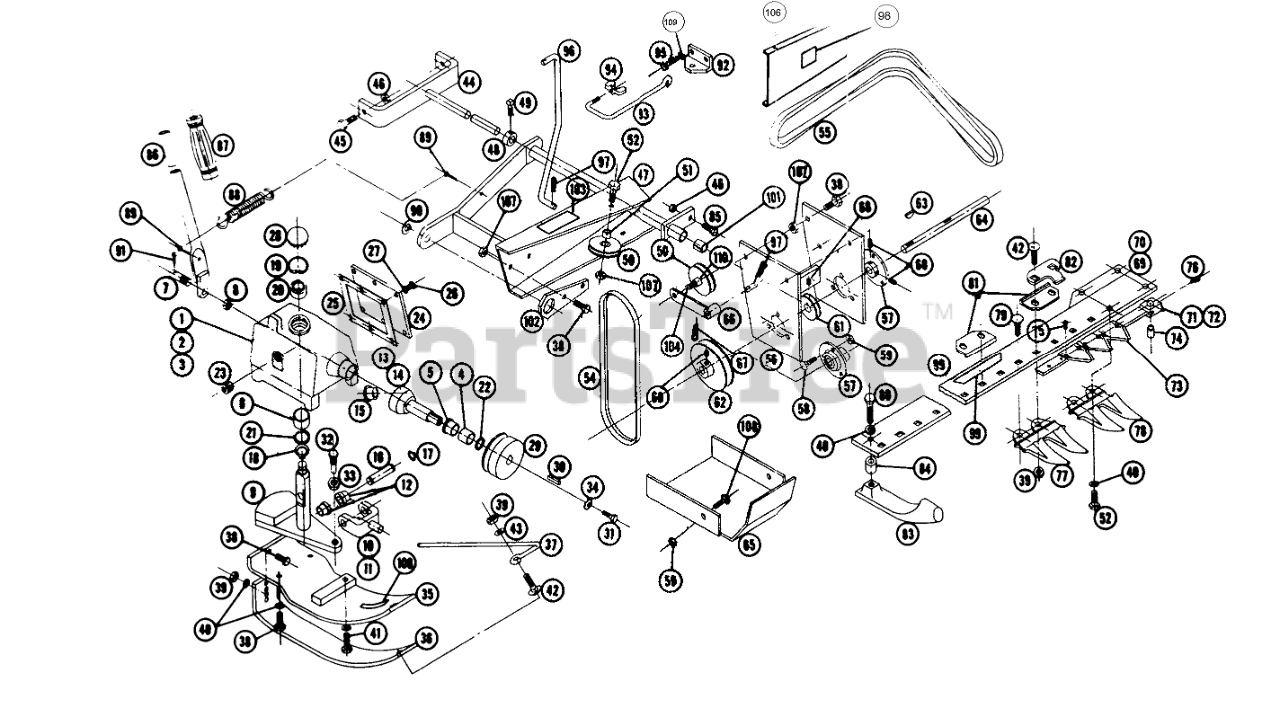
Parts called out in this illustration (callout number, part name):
1	Ass-y Housing Complete-Sickle Drive
2	Ass-y Housings & Bearings
3	Housing
4	Bearing-Bronze Sleeve
5	Bearing-Bronze Sleeve
6	Bearing-Bronze Sleeve
7	Pin
8	Nut, 3/4-16
9	Ass-y. Shaft-Weldment
10	Ass-y. Yoke
11	Yoke
12	Bearing-Bronze Sleeve
13	Ass-y. Shaft & Bearing
14	Shaft
15	Bearing-Bronze Sleeve
16	Pin Yoke
17	SNAP RING- 5/8 EXT
18	SNAP RING
19	Ring-Snap
20	Bearing-Ball
21	Seal 1 1/4 I.D.
22	Seal
23	Plug 1 x 11 1/2 NPTF
24	Cover Plate
25	Gasket
26	Screw-Rd. Hd. #10-24 x 3/8
27	Lockwasher #10
28	Plug Button
29	Pulley 4 Dia.
30	KEY-STRAIGHT
31	Bolt 3/8-16 x 7/8
32	Pin Sickle Drive
33	Nut-5/8-18
34	WASHER
35	Ass y. Shoe-Upper-Weldment
36	Shoe-Lower
37	Rod-Gross
38	Bolt 3/8-16 x 1
40	Lockwasher
41	Bolt, 3/8-16 x 1/2
42	Bolt Carriage 3/8-16 x 1
43	Washer
44	Ass-y. Bracket & Rod
45	Bolt Hex 1/2-13 x 1
46	Locknut-1/2-13
47	Ass-y Frame
48	Collar
49	Screw-Set
50	Pulley
51	SPACER
52	Bolt 3/8-16 x 1
54	Belt
55	V BELT
56	Ass-y. Shaft Support-Weldment
57	Bearing-Flanged
58	Bolt Hex 5/16-18 x 3/4
59	Nut-Nylock 5/16-18 Hex.
60	Set Screw 5/16-18 x 5/16
61	Pulley
62	Pulley
63	Key
64	Shaft
65	Shield Pulley
66	Ass-y. Idler Arm-Weldment
67	Hairpin
68	Set Screw 1/4-20 x 1/4
69	Ass-y. Cutter Bar Complete 42"
70	Ass-y. Bar-Guard
71	Ass-y. Knife Bar & Sections
72	Ass-y. Knife Bar-Weldment
73	Section
74	Bushing
75	Rivet
76	ZERK 90DEGREE
77	Twin Guard
78	Guard Cutter Bar
79	Bolt 3/8-16 x 1
80	Bolt, 3/8 16 x 2
81	Wear Plates
82	Clip, Hold Down
83	Skid
84	Spacer
85	Bolt-Hex. 1/2-13 x 2 3/4
86	Ass-y. Lever Lift
87	Grip
88	Spring
89	Cotter Pin
90	Washer
91	Cotter Pin 3/16 x 1
92	Bracket-Travel Hook
93	Hook-Travel Support
94	3/8 NC Wing Nut
95	Bolt-Hex 1/4-20
96	Rod-Lift
97	Hairpin
98	Decal
99	Decal
100	Decal
101	Bushing
102	Link
103	Decal-Caution
104	Bolt 3/8-16 x 1
105	Cover Belt
106	Screw Hex Self Tap #8-32 x 3/8
107	3/8-16 E.S.
108	Bolt-Car. 5/16-18 x 1
109	Lockwasher
110	SPACER
